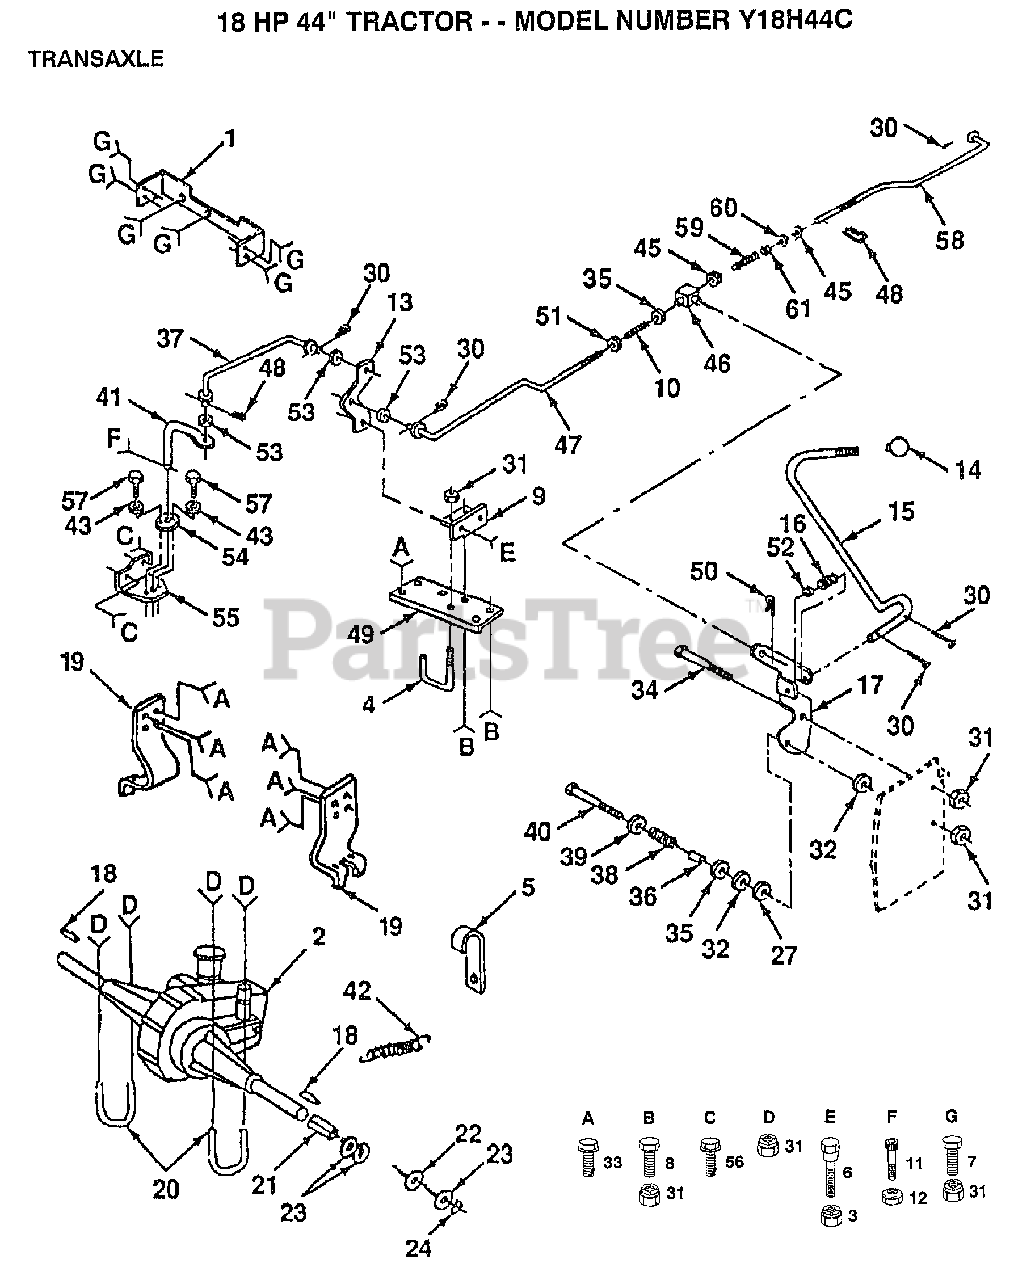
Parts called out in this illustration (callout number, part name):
1	PLATE TRANS SUPT
2	TRANSAXLE.ASM.214-1010S
4	KEEPER
5	CLIP T
6	SHOULDER BOLT LT
8	BOLT
9	BRKT BELLCRANK
10	SPRING GTV
11	SCREW
12	LOCKNUT
13	BELLCRANK
14	KNOB.DUCKHEAD.1/2
15	ROD.YTH
16	SPRING TORSION
17	BRKT CONTROL HYT
18	SQUARE KEY
19	BRKT TRANSAXLE
20	U BOLT
21	SPACER SPLIT
22	WASHER
23	WASHER
24	E-RING LT
27	WASHER HYT
30	COTTER PIN
32	WASHER FRIC HYT
33	SCREW
34	BOLT HYT
35	WASHER D
36	SPACER HYT
37	LINK CONTROL
38	SPRING HYT
39	WASHER
40	BOLT - HEX 3/8 - 16 X 3
41	ARM ASM PUMP
43	WASHER
45	NUT
46	TRUNION HYT
47	ROD ADJ CONTROL
48	RETAINER M
49	BRACKET
50	SPRING.RETAINER
51	WASHER T
52	WASHER
53	WASHER T
54	GUIDE CONTROL
55	BRKT
57	SCREW
59	SPRING ROD LT
60	WASHER
61	NUT
